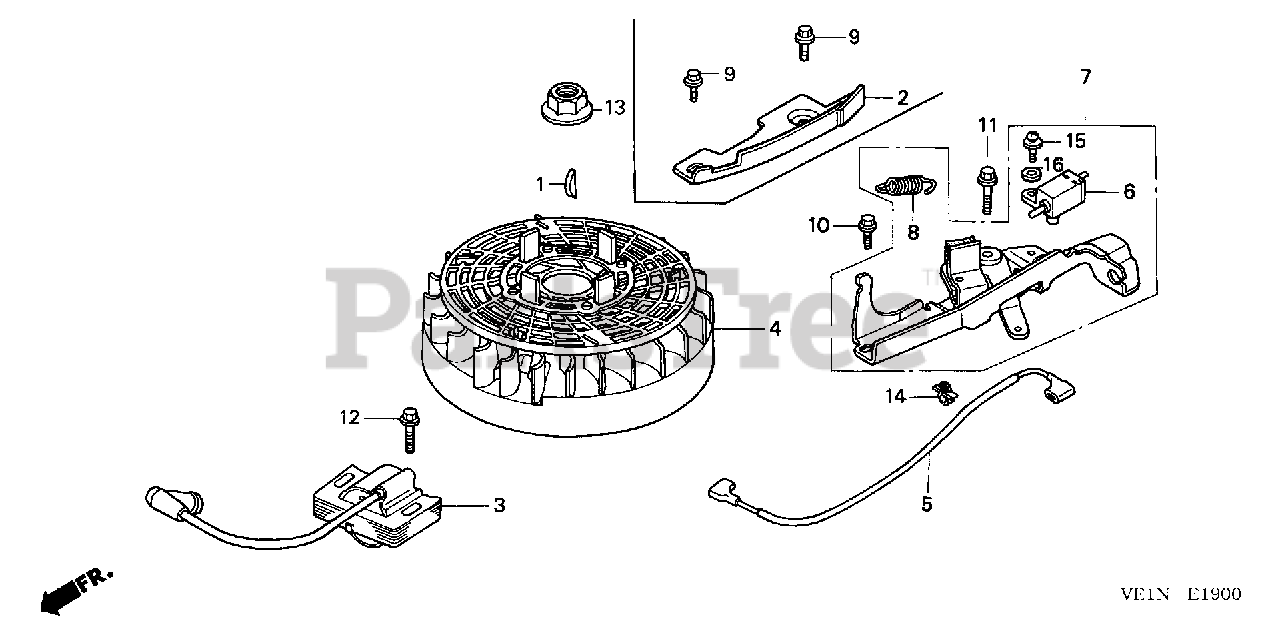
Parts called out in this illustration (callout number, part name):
1	KEY, SPECIAL WOODRUFF (25X18)
3	COIL ASSY., IGNITION (PHELON) (USE FOR F/W OF PHELON)
4	FLYWHEEL ASSY. (PHELON) (USE FOR IGN. COIL OF PHELON)
5	WIRE, STOP SWITCH
6	SWITCH ASSY., ENGINE STOP (N.C)
7	BRAKE ASSY.
8	SPRING, BRAKE LEVER
10	BOLT, FLANGE (6X14) (CT200)
11	BOLT, FLANGE (6X23) (CT200)
12	BOLT, FLANGE (6X20) (CT200)
13	NUT, FLANGE (14MM)
14	CLIP A, CABLE (3.8MM BLACK) (NIFCO)
15	SCREW-WASHER (4X12)
16	WASHER, PLAIN (4MM)
